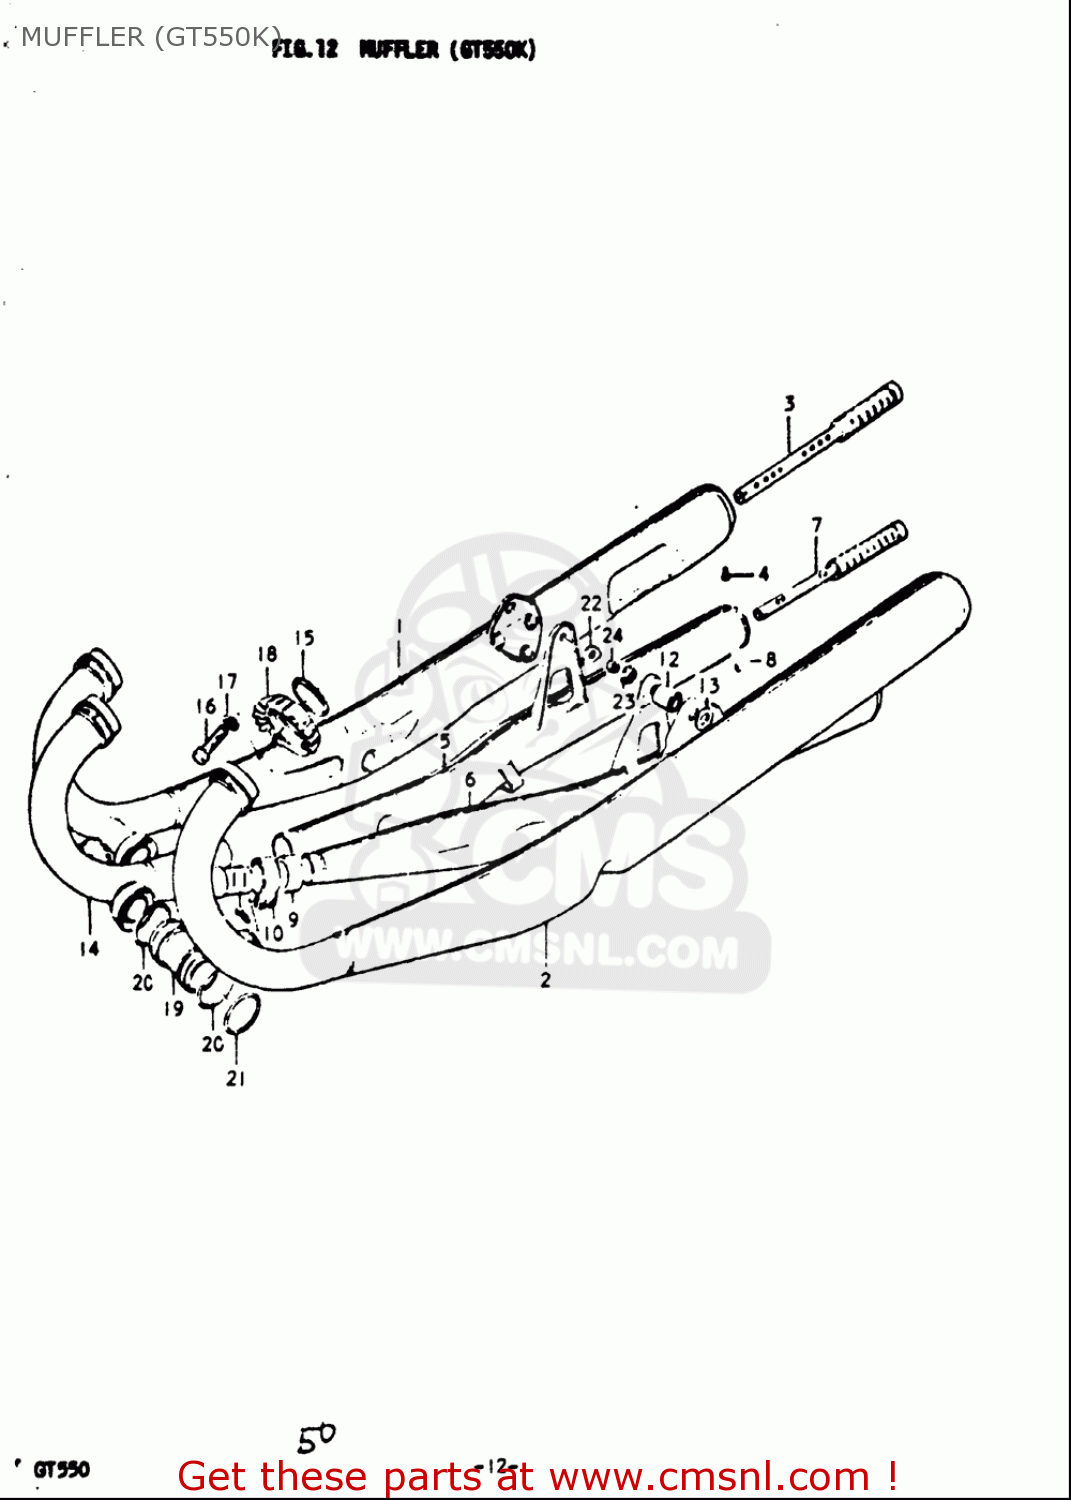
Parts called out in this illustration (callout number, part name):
3	PIPE,BAFFLE
4	SCREW(5X6)
7	PIPE,BAFFLE
8	SCREW(5X6)
9	CONNECTOR,MUFFLER
11	SCREW
12	BUSHING(10X23X35)
13	WASHER
15	GASKET,EXHAUST PIPE (NAS)
16	BOLT
17	WASHER,LOCK
20	O RING(D:2.6,ID:39.7)
22	DAMPER,MUFFLER SUPPORT BRACKET
23	NUT (M10X1.25X9)
24	SPACER(10.1X15X4.8)
